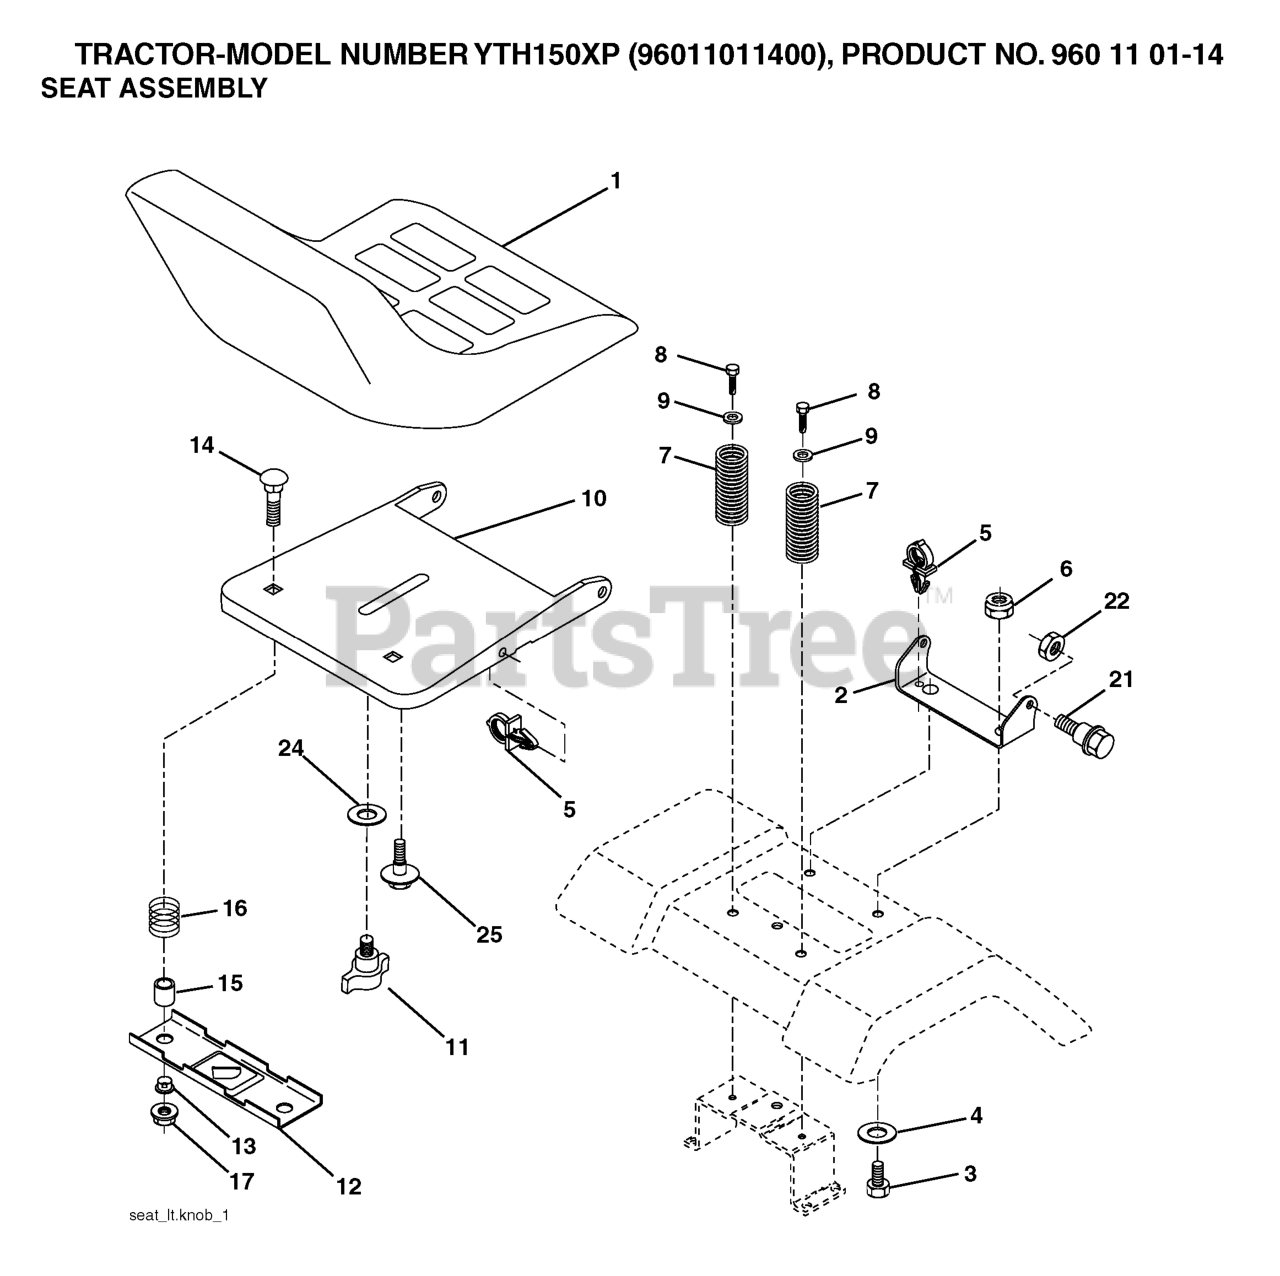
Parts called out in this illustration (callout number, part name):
1	SEAT.XH150.GRY
2	SEAT PIVOT BRKT
6	NUT
7	SPRING COMPRESSION
8	SCREW 3/8-16X1
9	WASHER
10	PAN.ASM.SEAT.1SLOT
11	KNOB.SEAT.ADJ.WINGNUT
12	BRKT.MNTNG.SWITCH.SEAT.BLACK
14	BOLT.ROUND.HEAD.SQUARE.NECK
15	SPACER SPLIT
16	SPRING COMPRESSED
17	NUT T
21	BOLT.SHOULDER.5/16-18
22	NUT.71038.31-18.HEX.NYLOCK
25	BOLT,SHOULD
41	STRAP
